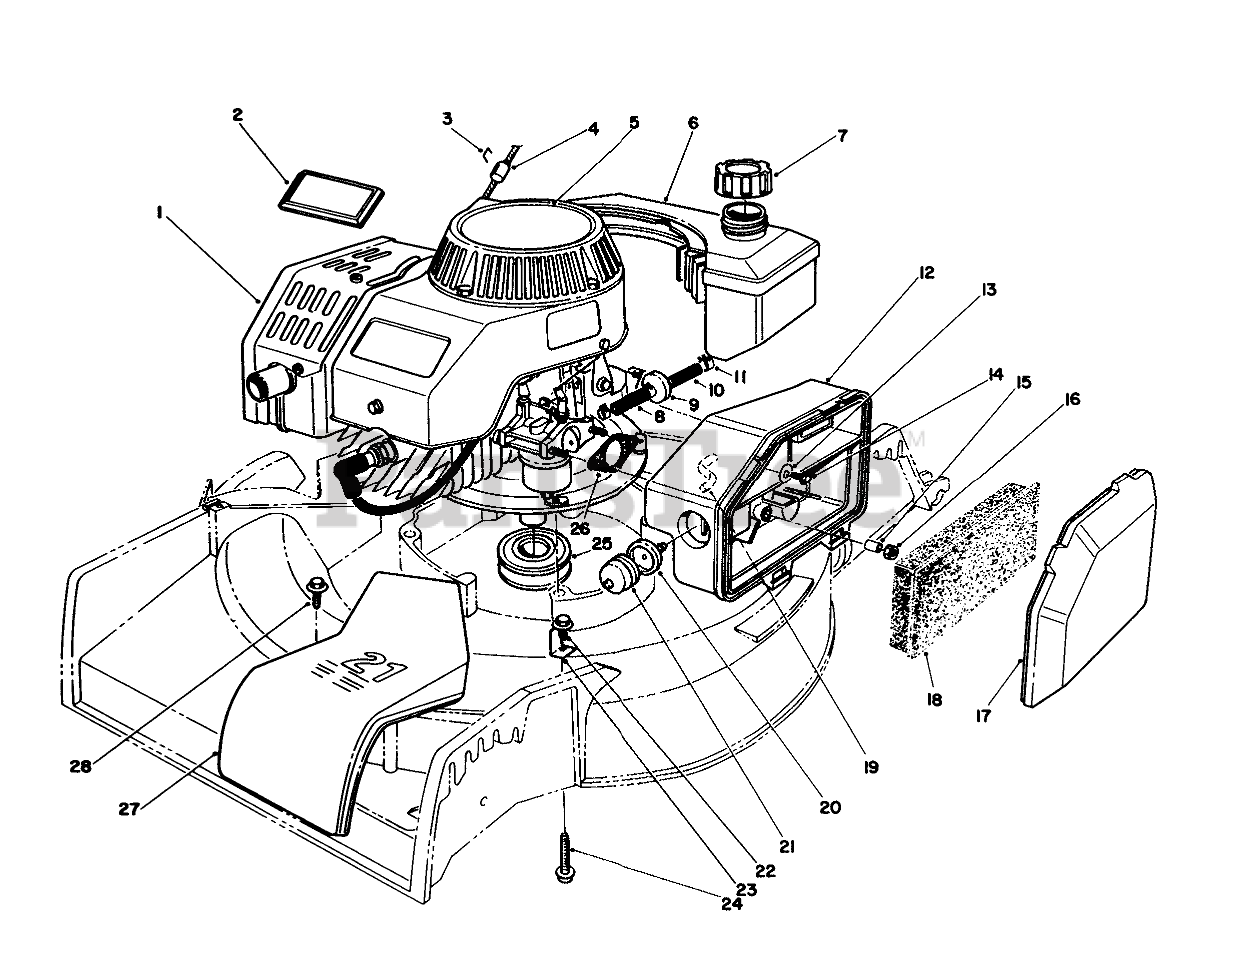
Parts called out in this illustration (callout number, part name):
1	Engine
2	TORO LOGO PLT
3	Staple
4	STOP-ROPE
5	DECAL - 2 CYC RECOIL
6	FUEL TANK ASM
7	GAS CAP ASM
8	HOSE-FUEL
9	FILTER-FUEL
10	HOSE-FUEL
11	CLAMP-FUEL LINE
12	BODY-AIR CLEANER
13	WASHER-FLAT
14	SCREW-HH
15	SPACER
17	COVER-AIR CLEANER
18	ELEMENT-AIR CLEANER
19	HOSE-PRIMER
20	BODY-PRIMER
21	BULB-PRIMER
22	SCREW-HWHTF
23	BELT GUIDE
24	SCREW-HHF, WHIZ
25	PULLEY-DRIVER
26	GASKET-AIR CLEANER
27	BELT COVER 21" S D
28	SCREW
